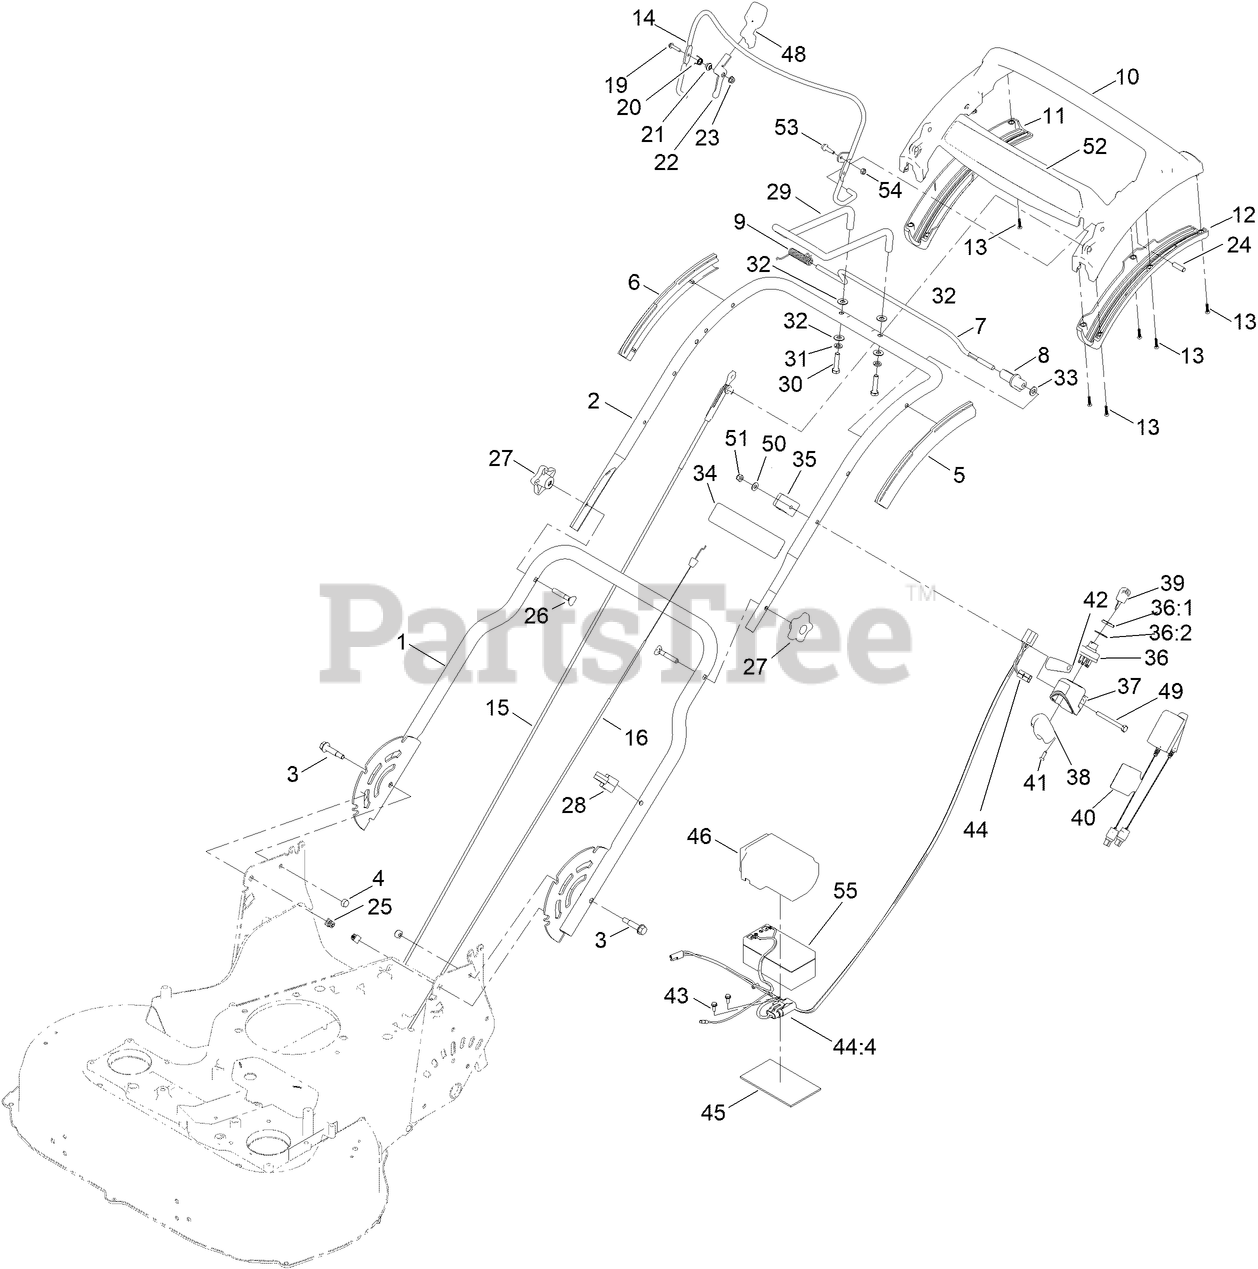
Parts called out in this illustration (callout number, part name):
1	HANDLE-LOWER, ASM
2	HANDLE-UPPER
3	BOLT-SHOULDER, HHF
4	NUT-LOCK, NI
5	GUIDE-CURVED, LH (RWD)
6	GUIDE-CURVED, RH (RWD)
7	ROD-CONTROL, TRACTION
8	LEVER-TRACTION, RWD
9	SPRING-TORSION
10	HANDLE-PERSONAL PACE, CURVED
11	BOTTOM-HANDLE, RH
12	BOTTOM-HANDLE, LH
13	SCREW-PPH
14	BAIL-BRAKE [BLACK]
15	CABLE-BRAKE
16	CABLE-TRACTION
19	SCREW-HWH
20	SPRING-TORSION
21	SPACER
23	NUT-LOCK, FLANGE
24	PIN-HANDLE, PP
25	PLUG-SQUARE
26	SCREW-HANDLE
27	KNOB-HANDLE
28	GUIDE-CABLE
29	HANDLE-ASSIST, STEEL
30	SCREW-HH
31	WASHER-LOCK
32	WASHER
33	WASHER-PLAIN
34	DECAL-BATTERY CHARGING
35	ANCHOR-CABLE
36	SWITCH-STARTER
36:1	NUT-HH
36:2	WASHER-LOCK
37	HOUSING-SWITCH, KEY
38	COVER-SWTCH
40	CHARGER, BATTERY (12V)
41	SCREW-PLASTIC, PPH
42	DECAL-SWITCH, IGNITION
43	SCREW-TAPTITE
44	HARNESS-WIRE
44:4	FUSE-40 AMP
45	FOAM-BATTERY
46	COVER-BATTERY
49	SCREW-HH
50	WASHER-FLAT
51	NUT-LOCK, NI
52	DECAL-HANDLE, PP
53	SCREW-SHOULDER
54	NUT-HEX
55	BATTERY-WET
